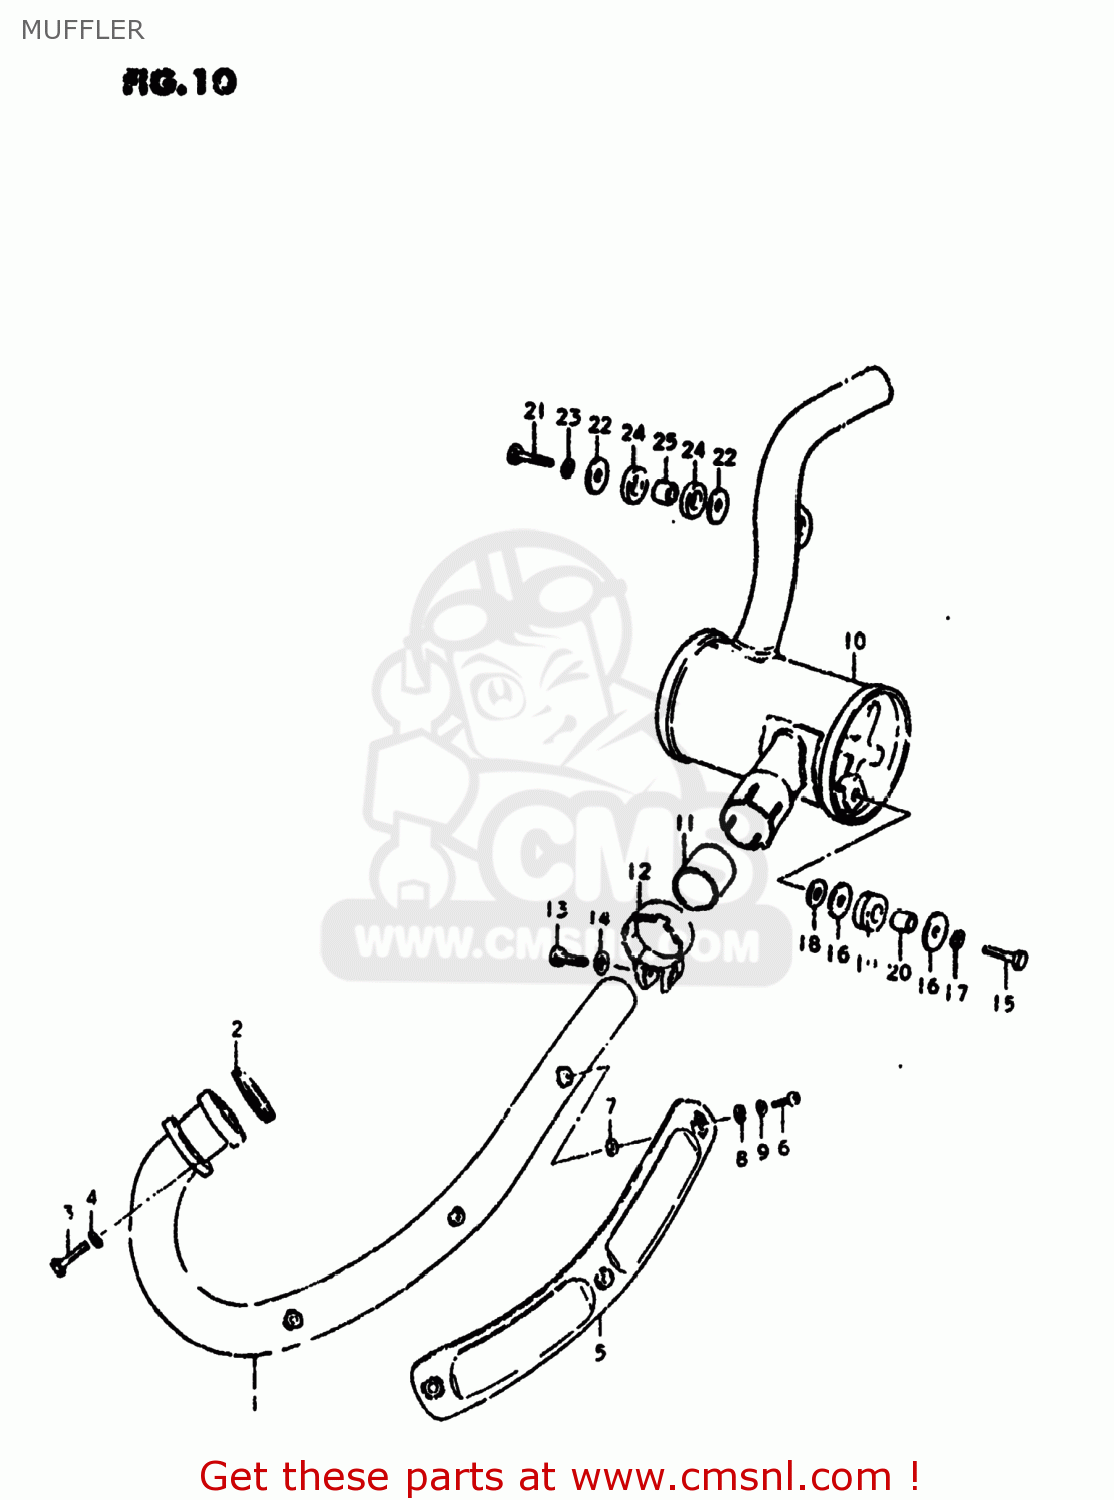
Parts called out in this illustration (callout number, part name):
1	PIPE,EXHAUST
2	GASKET,EXHAUST PIPE (NAS)
3	BOLT
4	LOCK WASHER
5	COVER,EXHAUST PIPE
6	SCREW
7	GASKET 6.2X12X1.5 (MCA)
8	WASHER
9	LOCK WASHER
10	BODY,MUFFLER
11	CONNECTOR,MUFFLER
12	CLAMP,MUFFLER CONNECTOR
13	BOLT 8X35
14	WASHER
15	BOLT (8X30)
16	WASHER (8.5X29X1.6)
17	LOCK WASHER
18	GASKET
19	CUSHION
20	SPACER (8.6X13.8X13)
21	BOLT(8X27)
22	WASHER (8.5X29X1.6)
23	LOCK WASHER
24	CUSHION
25	SPACER (8.6X13.8X13)
